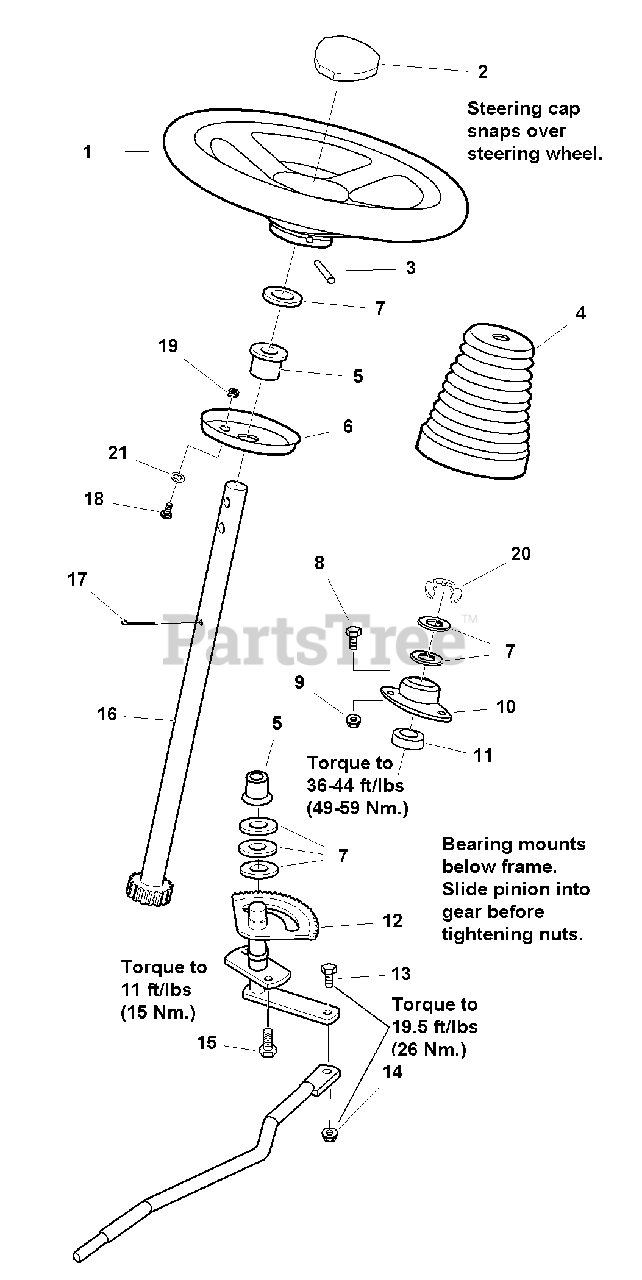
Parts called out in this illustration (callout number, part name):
1	STEERING WHEEL, Straight Shaft
2	CAP, Steering Wheel, Plain
3	PIN, Spring
4	COVER, Black Rubber
5	BUSHING
6	PLATE, Mounting Steering
7	WASHER
8	CAPSCREW, Hex Head Flange Lock, 3/8-16 x 3/4
9	NUT, Hex Whiz Lock, 3/8-16
10	BEARING, Flange
11	SPACER
12	GEAR & SHAFT ASSEMBLY
13	CAPSCREW, Hex Head, 3/8-16 x 1-1/4
14	NUT, Hex Flange Lock, 3/8-16
15	CAPSCREW, Hex Head Taptite, 5/16-18 x 3/4
16	SHAFT ASSEMBLY
17	PIN, Cotter
18	CARRIAGE BOLT, 5/16-18 x 1 1/4
19	NUT, Hex, 5/16-18
20	RING, Clipring Extension
21	PUSHNUT, 5/16
